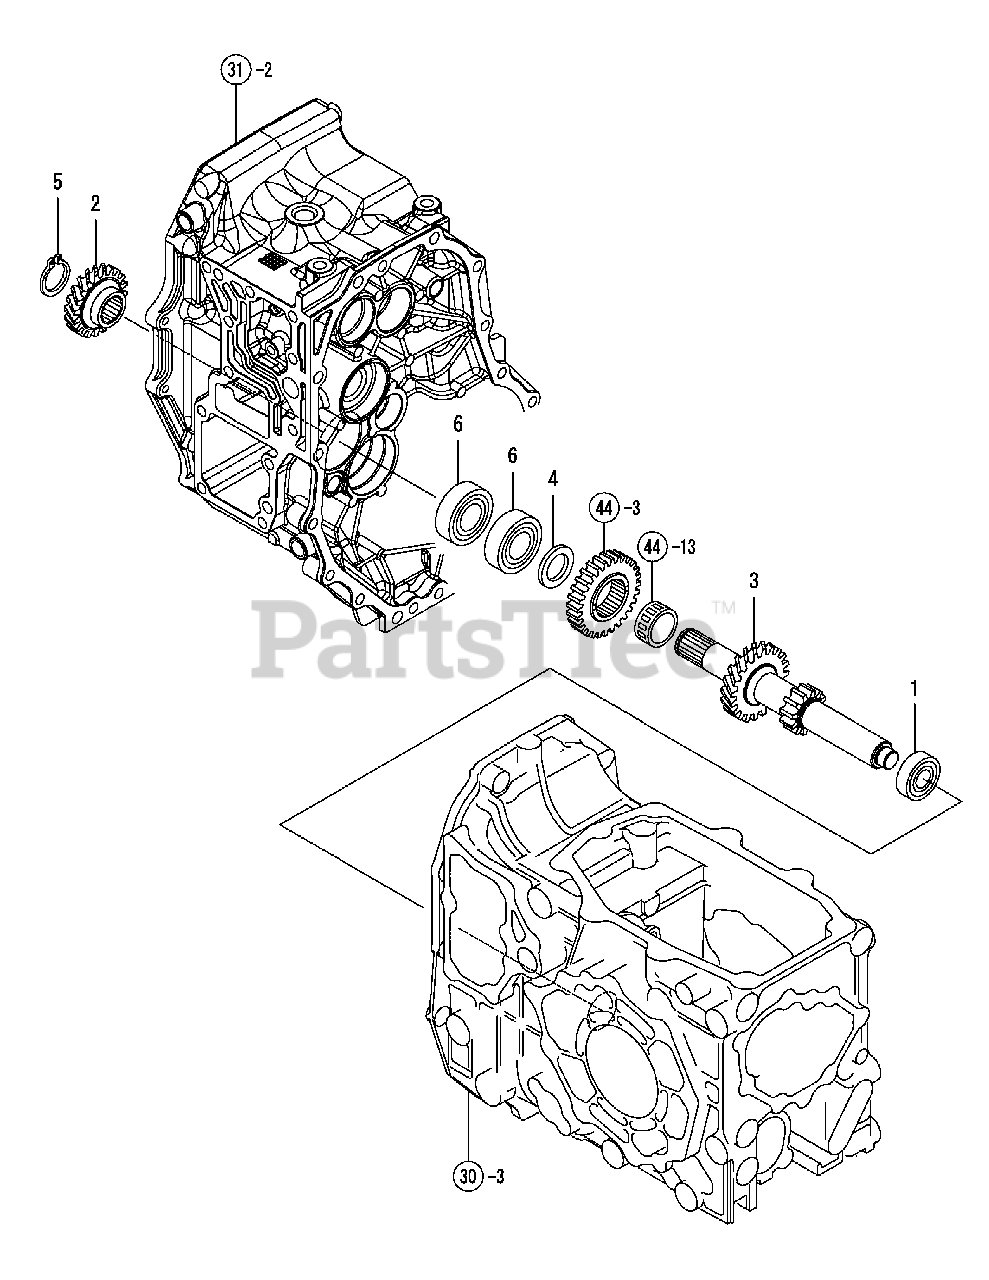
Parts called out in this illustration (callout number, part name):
2	Gear, Driven Z=21
3	Shaft Main, For Front Drive
4	Thrust Washer (C)
